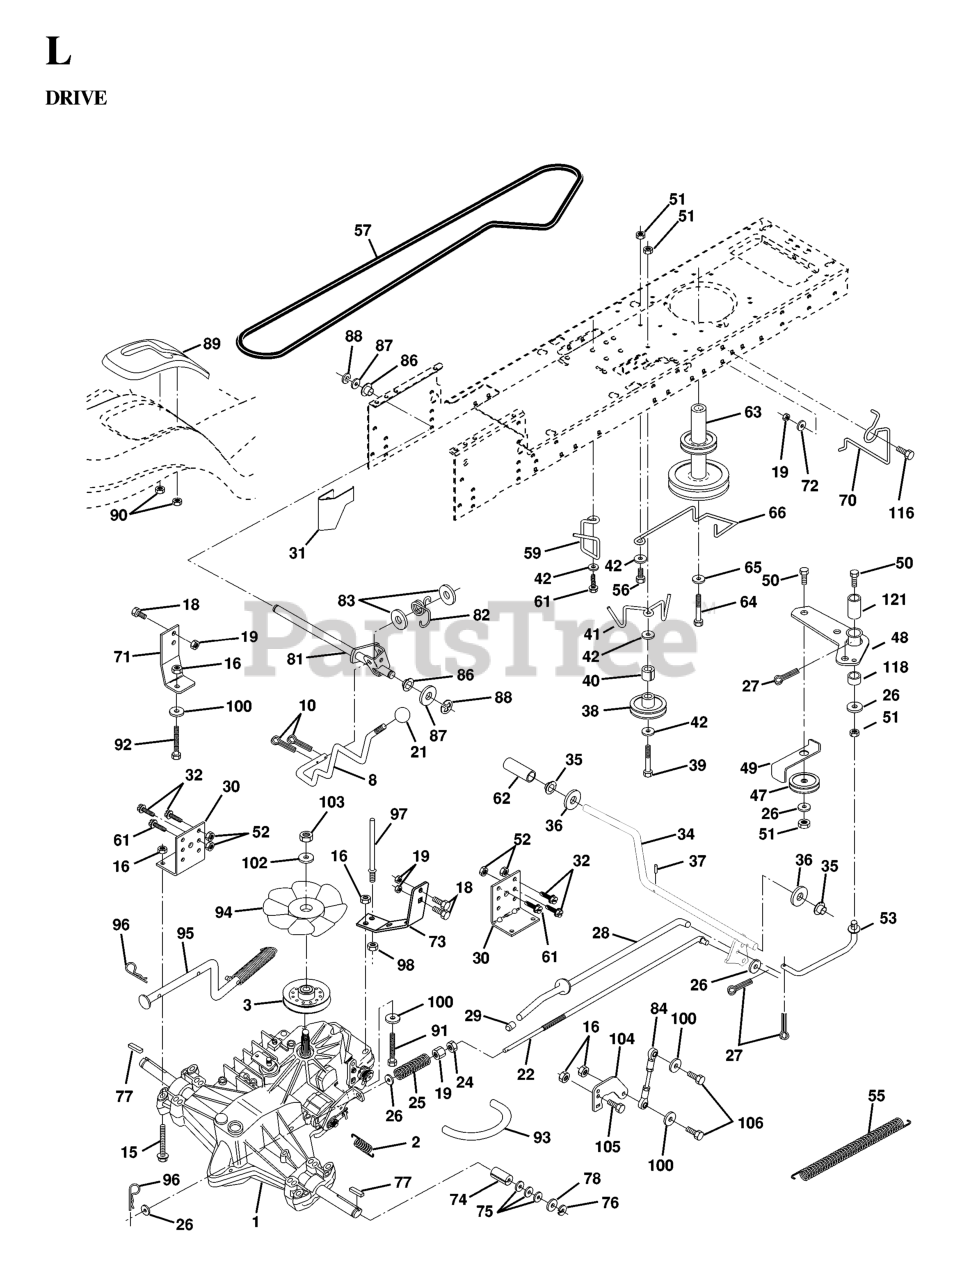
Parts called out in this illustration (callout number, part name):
1	TRANSAXLE ASSEMBLY
2	SPRING BRAKE
3	PULLEY, TRANSAXLE
8	ROD SHIFT FENDER
10	PIN COTTER
15	BOLT HEX 5/16-18 GR 5
16	NUT.71038.31-18.HEX.NYLOCK
19	NUT
21	KNOB.DUCKHEAD.1/2
22	ROD BRAKE HYDRO
24	NUT
25	SPRING ROD LT
26	WASHER
27	COTTER PIN
28	ROD BRAKE PARK LT
29	PLUNGER CAP
30	BRACKET TRANSAXLE
31	KEEPER BELT LH
32	BOLT
34	SHAFT, FOOT PEDAL
35	BEARING.NYLON
37	DRIVE PIN
38	PULLEY.IDLER.FLAT
41	KEEPER, BELT IDLER
42	WASHER
47	IDLER PULLEY
48	BELLCRANK ASSEMBLY
49	RETAIN BELT
50	BOLT
52	LOCKNUT
53	LINK, CLUTCH LT
55	SPRING, RETURN LT
57	BELT
59	KEEPER CENTER SPAN
61	SCREW
62	COVER, PEDAL (1 2)
63	PULLEY.ENG.CL.MECH.SLVR.LT/YT
64	REPL BY 871 17 07-64
65	LOCKWASHER
66	KEEPER BELT ENGINE
70	KEEPER BELT ENG
71	STRAP LH TORQUE
72	WASHER
73	STRAP TORQUE RH HYDRO
74	SPACER SPLIT
77	SQUARE KEY
81	SHAFT ASSY
82	SPRING,TORSION
83	WASHER
84	ROD.TIE.BALL.4.75
86	BUSHING.STEERING.ROD LTB-WSL
89	CONSOLE SHIFT
90	NUT.PUSH.3/16
91	BOLT.FIN HEX 5/16-18UNC X2 1/4
92	HEX BOLT
93	LINE FUEL HYD 4"
94	FAN 7" HYDRO
95	CONTROL ARM, BYPASS HYDRO
96	RETAINER M
97	KEEPER BELT RH
100	WASHER M
103	NUT.HEX.1/2-20
104	CONTROL ARM
106	BOLT.5/16-18X1-1/4 FULL.THREAD
116	BOLT
118	SPACER BELLCRANK
121	NYLINER CLUTCHING
